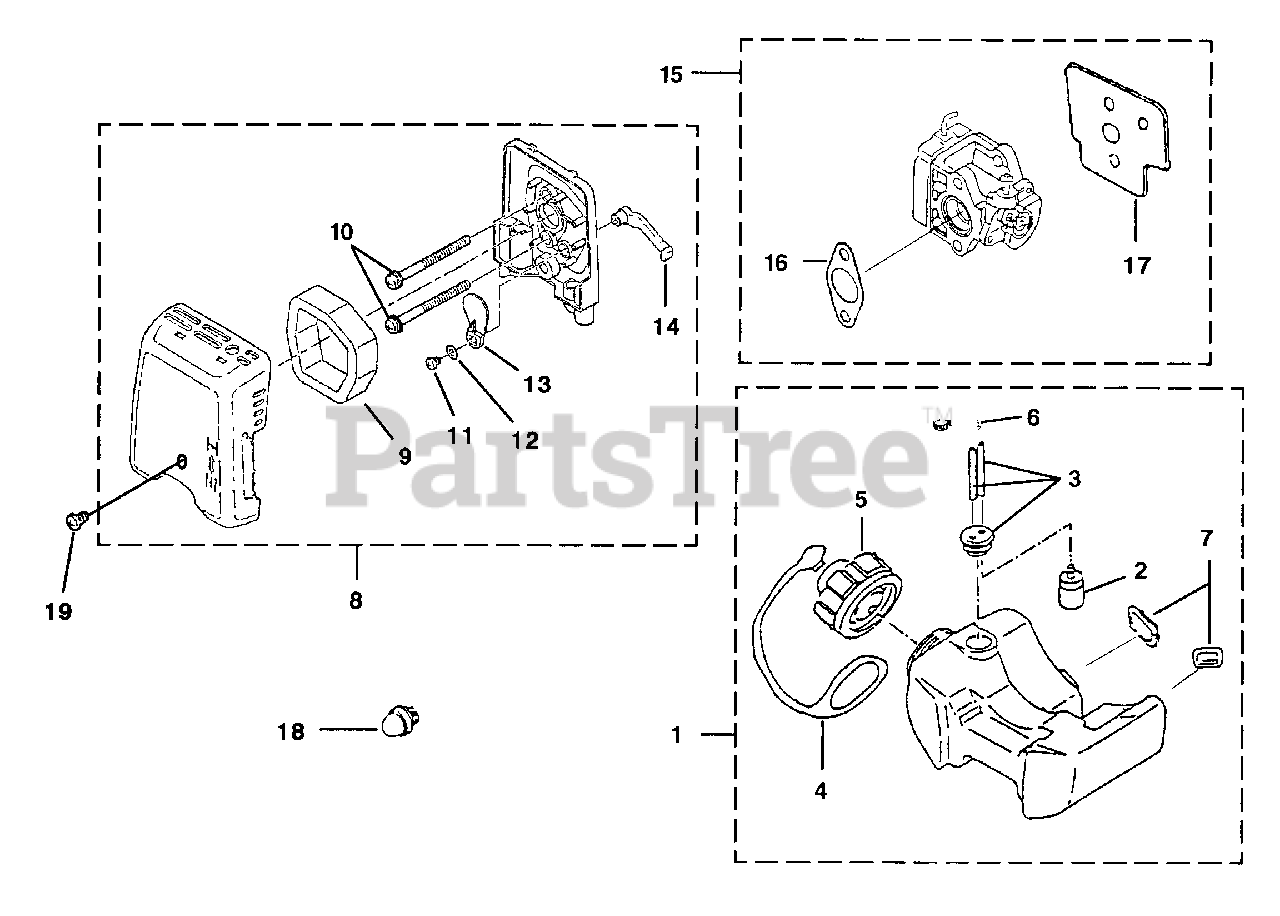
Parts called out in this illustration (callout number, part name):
1	FUEL TANK ASSEMBLY
2	FILTER-Fuel
4	CAP-Retainer
5	CAP-Fuel
6	CLAMP, Hose
7	BUMPER KIT
8	AIR FILTER ASSEMBLY
9	FILTER, Air
10	SCREW (M5 x 62)
11	SCREW, Tapping (M4 x 8)
13	CHOKE PLATE
14	CHOKE LEVER
15	CARBURETOR ASSEMBLY
16	GASKET-Carburetor
17	INSULATOR-Gasket
18	PRIMER BULB
19	SCREW (M5 x 14 W SW)
